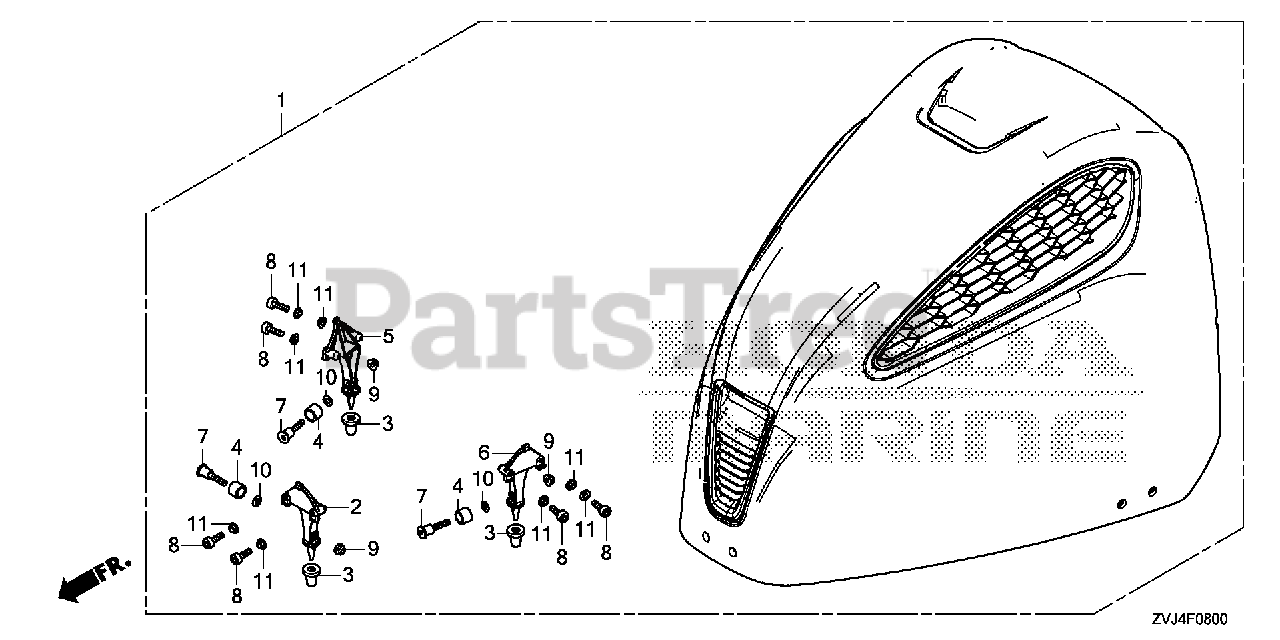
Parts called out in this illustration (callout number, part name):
1	COVER ASSY., ENGINE *NH565* (GRAND PRIX WHITE)
1	COVER ASSY., ENGINE *NHB14M* (AQUA MARINE SILVER METALLIC)
2	BRACKET, FR. HOOK
3	GROMMET, LOCK HOOK
4	ROLLER, HOOK
5	BRACKET, R. HOOK
6	BRACKET, L. HOOK
7	BOLT, SOCKET (6X25)
8	BOLT, SOCKET (6X20)
9	NUT, SELF-LOCK (6MM)
10	WASHER, PLAIN (6MM) Use up to Frame SN 4800342.
11	COLLAR, DISTANCE (6.5X9X3)
